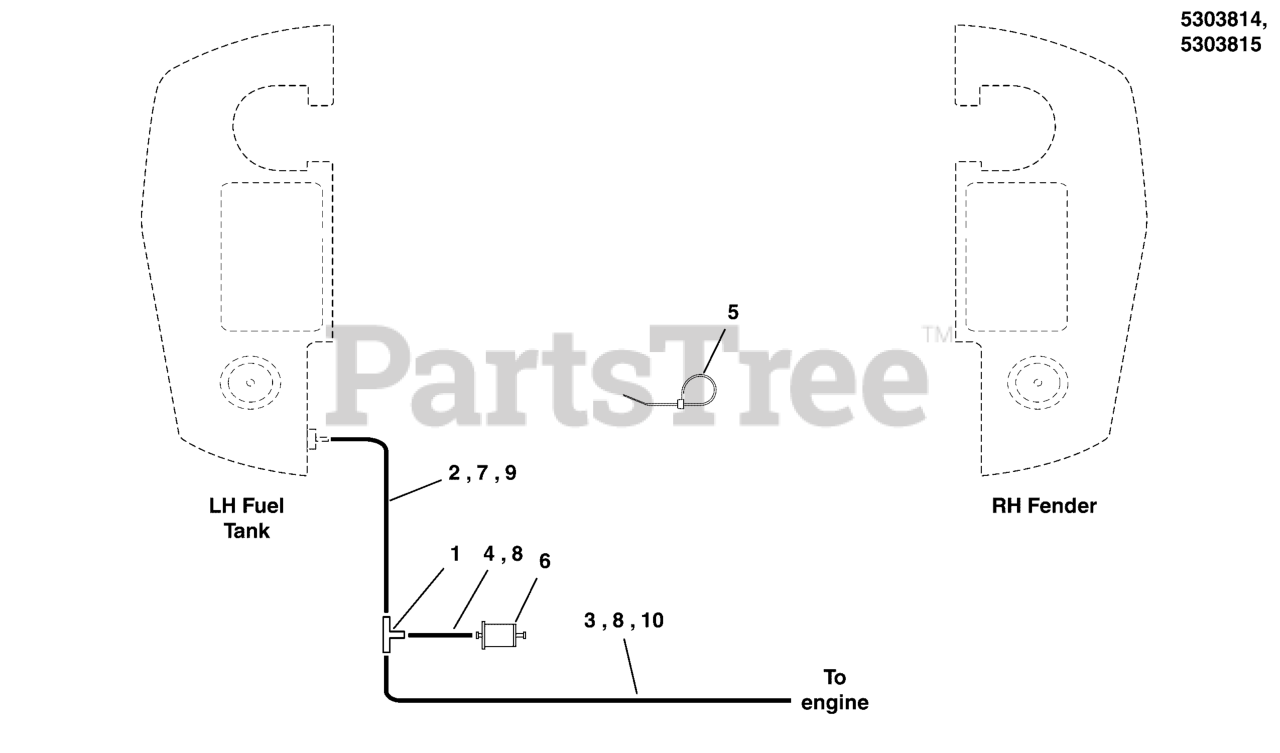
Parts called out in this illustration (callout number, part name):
1	FITTING, 3/16" TEE, BARB TYPE, HDPE
2	HOSE, VAPOR, 5MM ID, 33.00 LG
3	HOSE, VAPOR, 5MM ID, 10.00 LG
4	HOSE, VAPOR, 5MM ID, 2.00 LG
5	TIE,SELF-LOCKING, 6"
6	FILTER, FUEL
7	HOSE, VAPOR, 5MM ID, 15.00 LG
8	HOSE, VAPOR, 5MM ID, 18.00 LG
9	HOSE, VAPOR, 5MM ID, 34.00 LG
10	HOSE, VAPOR, 5MM ID, 16.00 LG
